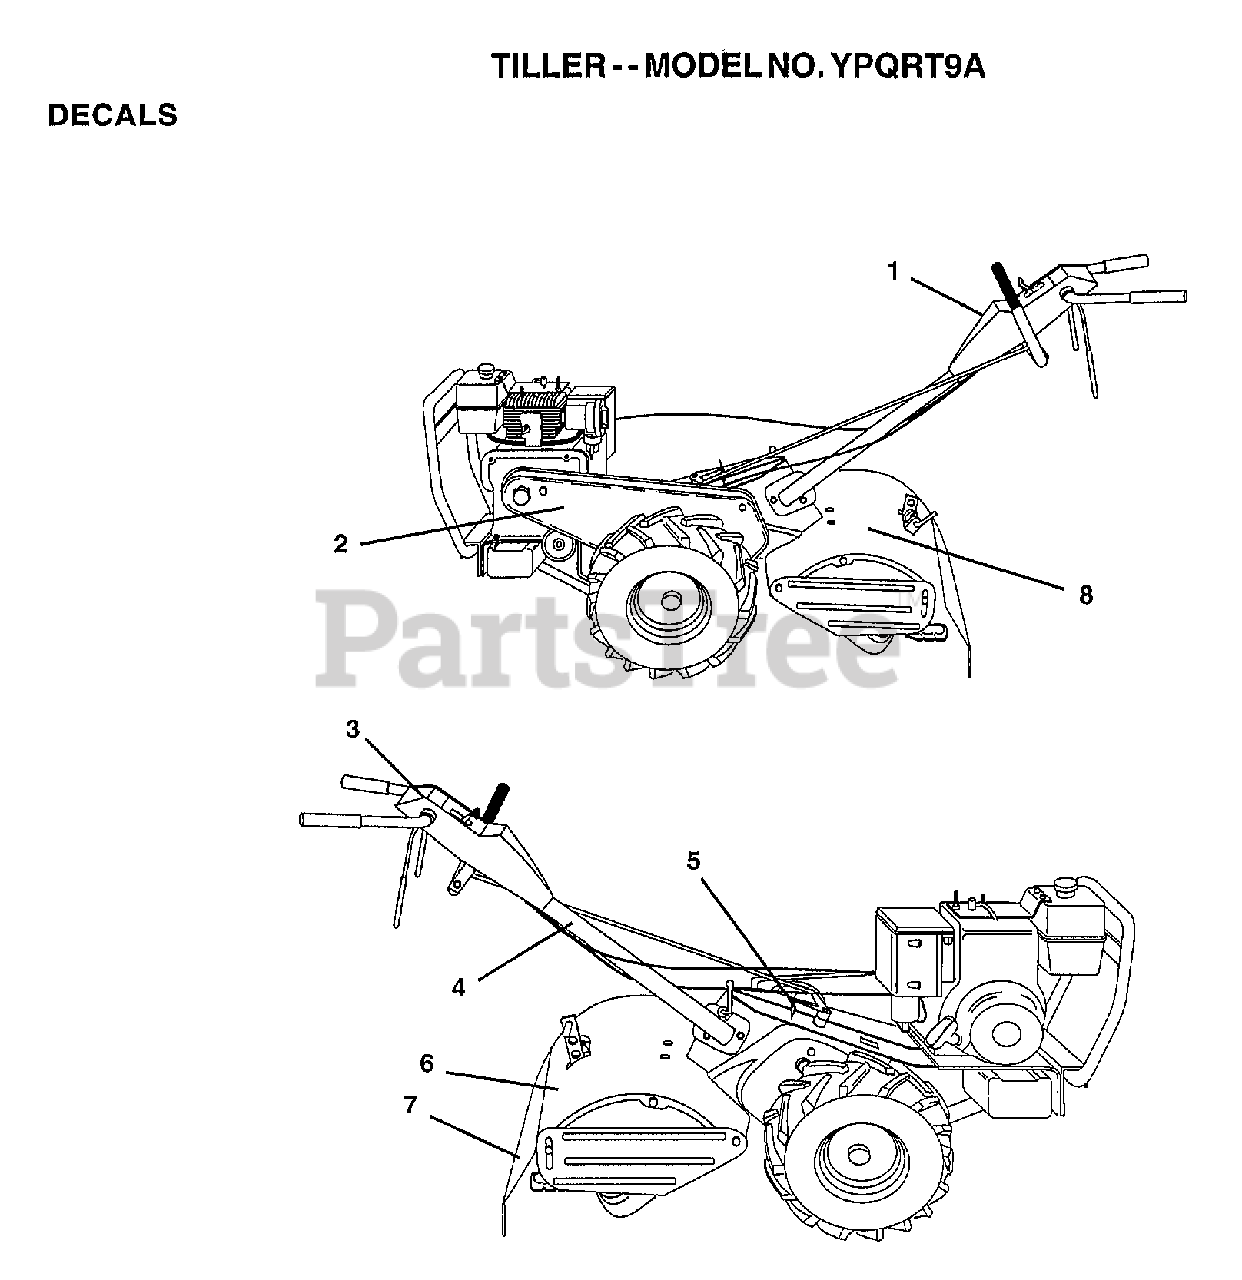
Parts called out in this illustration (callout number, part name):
1	DECAL PANEL CNTRL
2	DECAL GUARD BELT
3	DECAL INST PNL 21
4	DECAL TI
5	DECAL.SHIFT.IND.
6	DECAL.CAUTION
8	DECAL SHIELD TINE
